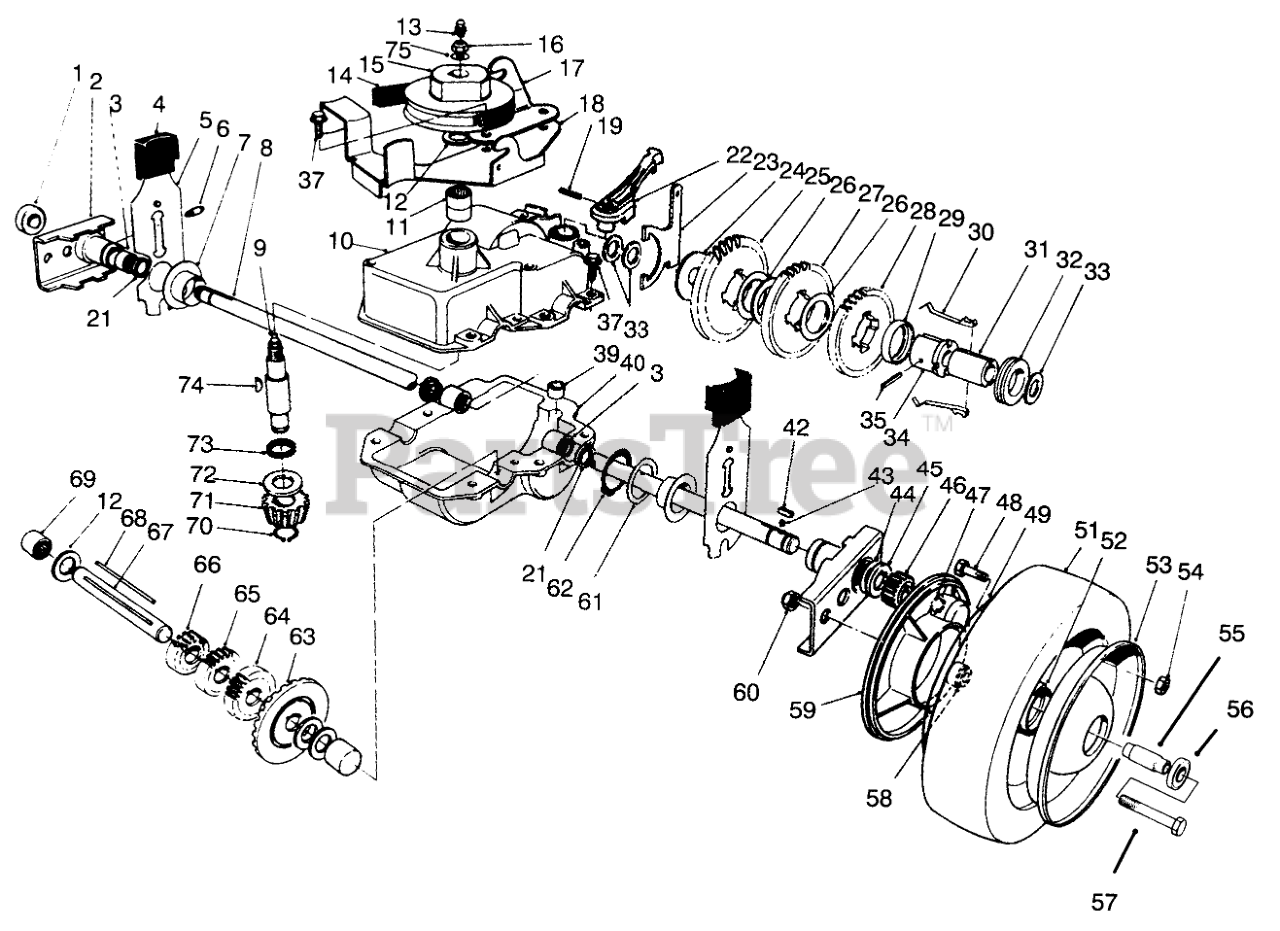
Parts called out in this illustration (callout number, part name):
1	BEARING-WHEEL
2	Pivot Arm Assembly (Incl. Ref. #1, 3, 6 & 21)
3	BEARING-ROLLER
4	KNOB-ARM
5	REAR SPRING ARM ASM
7	CAP-END
8	SHAFT-OUTPUT
9	Shaft-Input (Incl Ref. #13)
10	Upper Case Assembly (Incl. Ref. #11 & 73)
11	BEARING-NEEDLE
12	WASHER-THRUST
13	FITTING-GREASE, ZERK
14	V-BELT
15	PULLEY
16	NUT-HEX
17	Bracket-Traction Engage
18	Belt Guide Bracket
19	PIN-COIL
21	SEAL-OIL
22	LEVER-SHIFT
23	YOKE-SHIFT
24	WASHER
26	WASHER
27	GEAR-42T
28	GEAR-38T
29	RETAINER-KEY
30	KEY-SHIFT
31	SLEEVE
32	COLLAR-SHIFT
33	WASHER-PLAIN
34	SLEEVE-GEAR
35	PIN-GROOVE
37	SCREW-HWHTF
39	BUSHING-YOKE
40	CASE-GEAR, LOWER
43	SPRING-COMPRESSION
44	WASHER-THRUST, OUTER
45	WASHER-THRUST, OUTER
46	GEAR-PINION
47	RING-RETAINING
48	SCREW-HH
49	Wheel-Half
52	HUB-BEARING
53	Wheel-Half
54	NUT-LOCK, NI
55	SPACER-BEARING
56	BEARING-WHEEL
57	SCREW-HH
58	SPACER-COVER, WHEEL
59	COVER-WHEEL
60	NUT-LOCK, CONE
61	WASHER
62	RING-RETAINING
63	GEAR-BEVEL
64	GEAR-18T
65	GEAR-14T
66	GEAR-12T
67	SHAFT-INTERMEDIATE
69	BEARING-NEEDLE, CLOSED
70	RING-RETAINING
71	PINION-BEVEL
72	WASHER-THRUST
74	KEY-WOODRUFF
75	WASHER-FLAT
